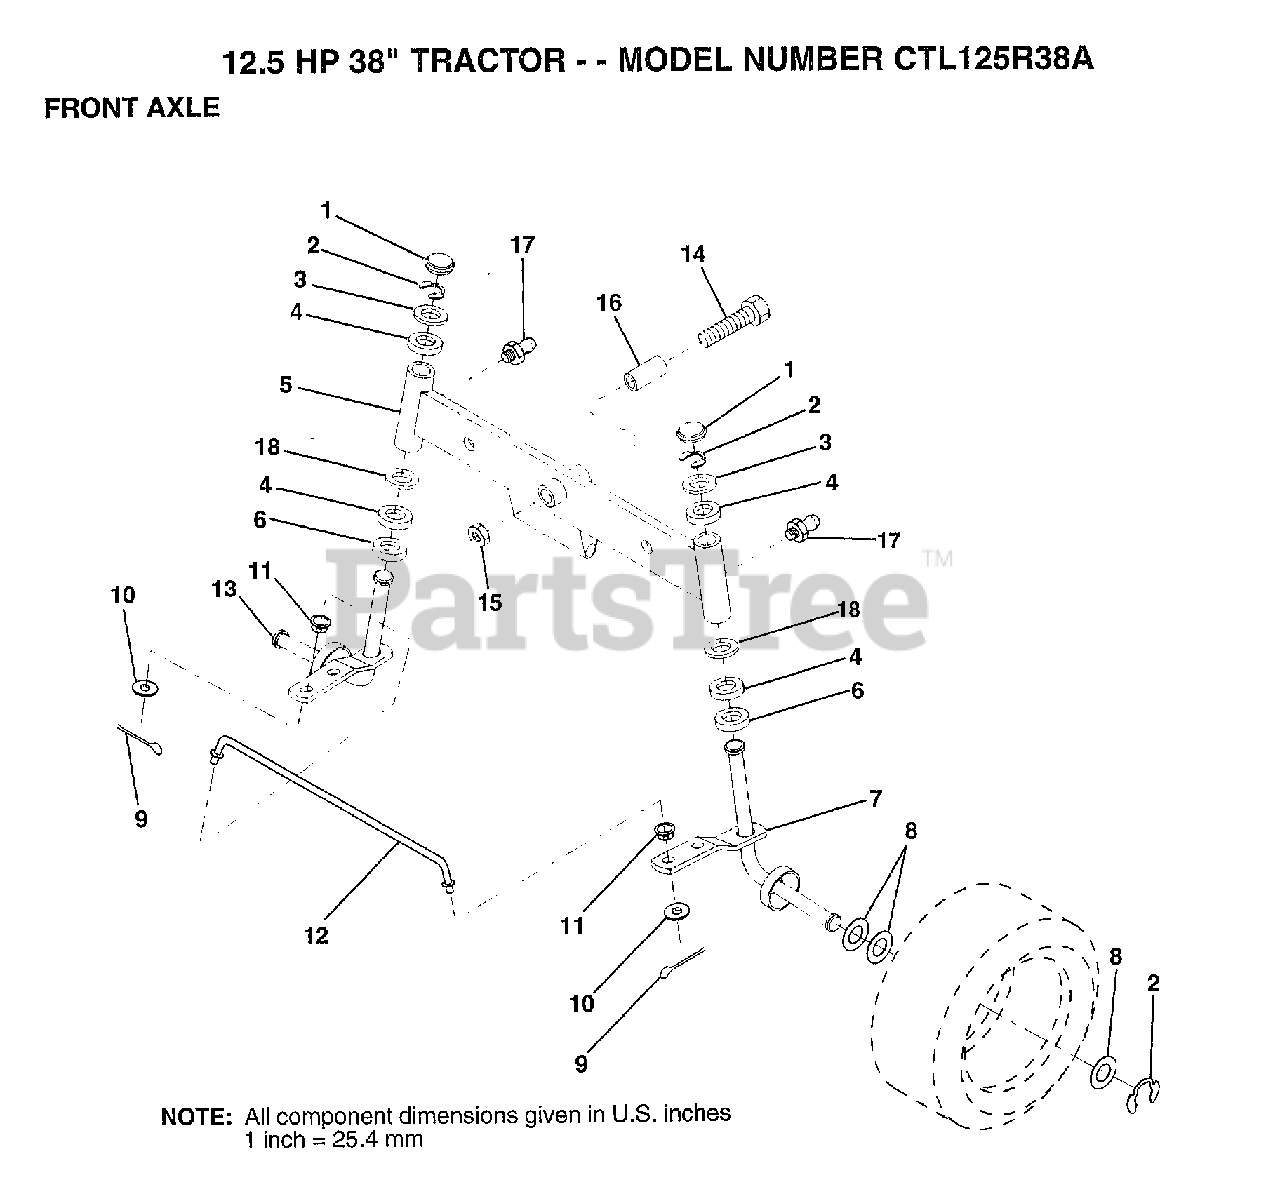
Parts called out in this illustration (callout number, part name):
1	CAP
2	RING
3	WASHER
4	COL. SRTG. BEAR.
6	WASHER .T
7	SPINDLE ASM RH
8	WASHER
9	COTTER PIN
10	WASHER
11	BUSHING.DRAGLINK
12	TIE ROD
13	SPINDLE ASM LH
14	BOLT HEX 5/8-11
15	"NUT-LOC,FLANGE LT"
16	SPACER, BEARING, FRONT AXLE
17	ZERK M
18	WASHER
